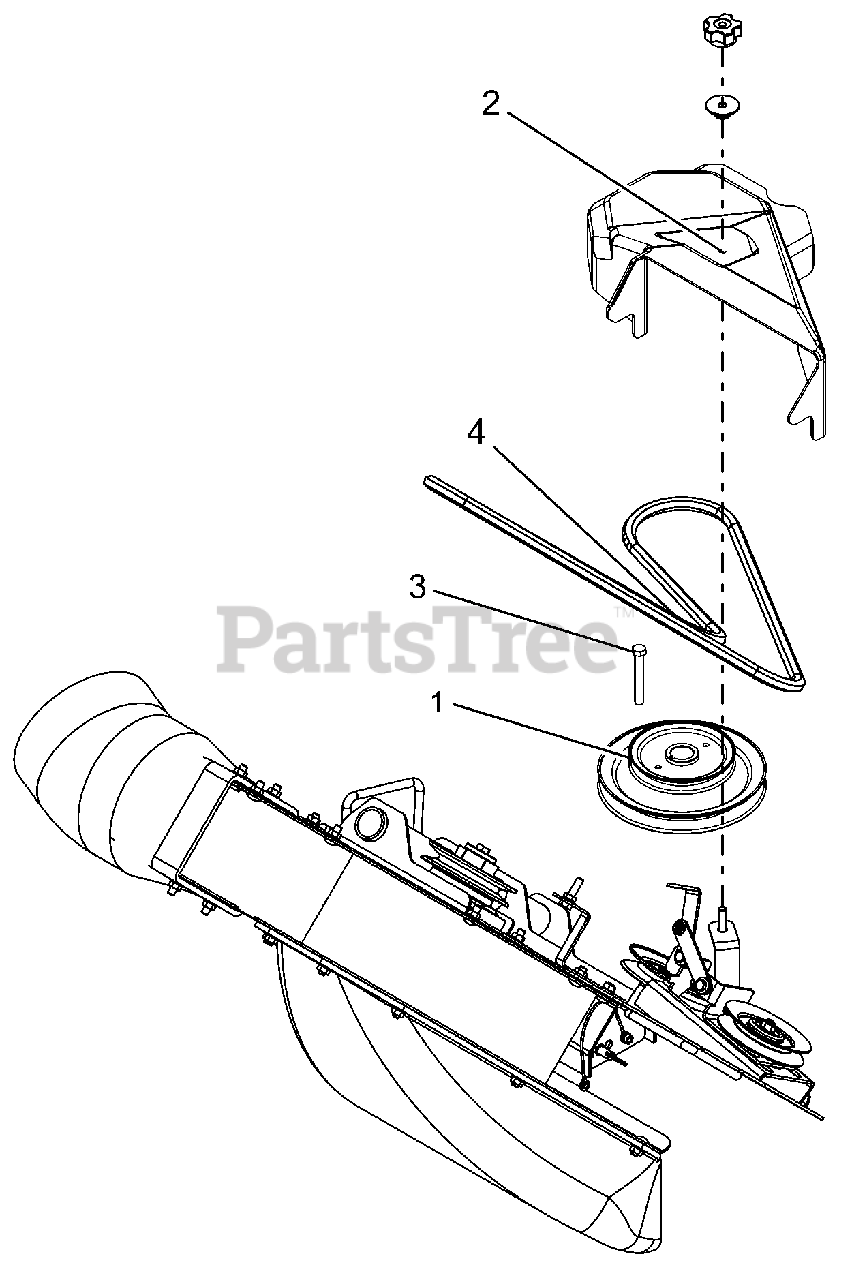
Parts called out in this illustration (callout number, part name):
1	PULLEY, DOUBLE 1"ID X 7.50"OD & 4.75"OD (BLACK)
2	COVER, BELT 60 BLOWER
3	BLT-HEX .38-16X2.75 GR8 YWZC
4	HEX BELT, AA-WRAPPED
